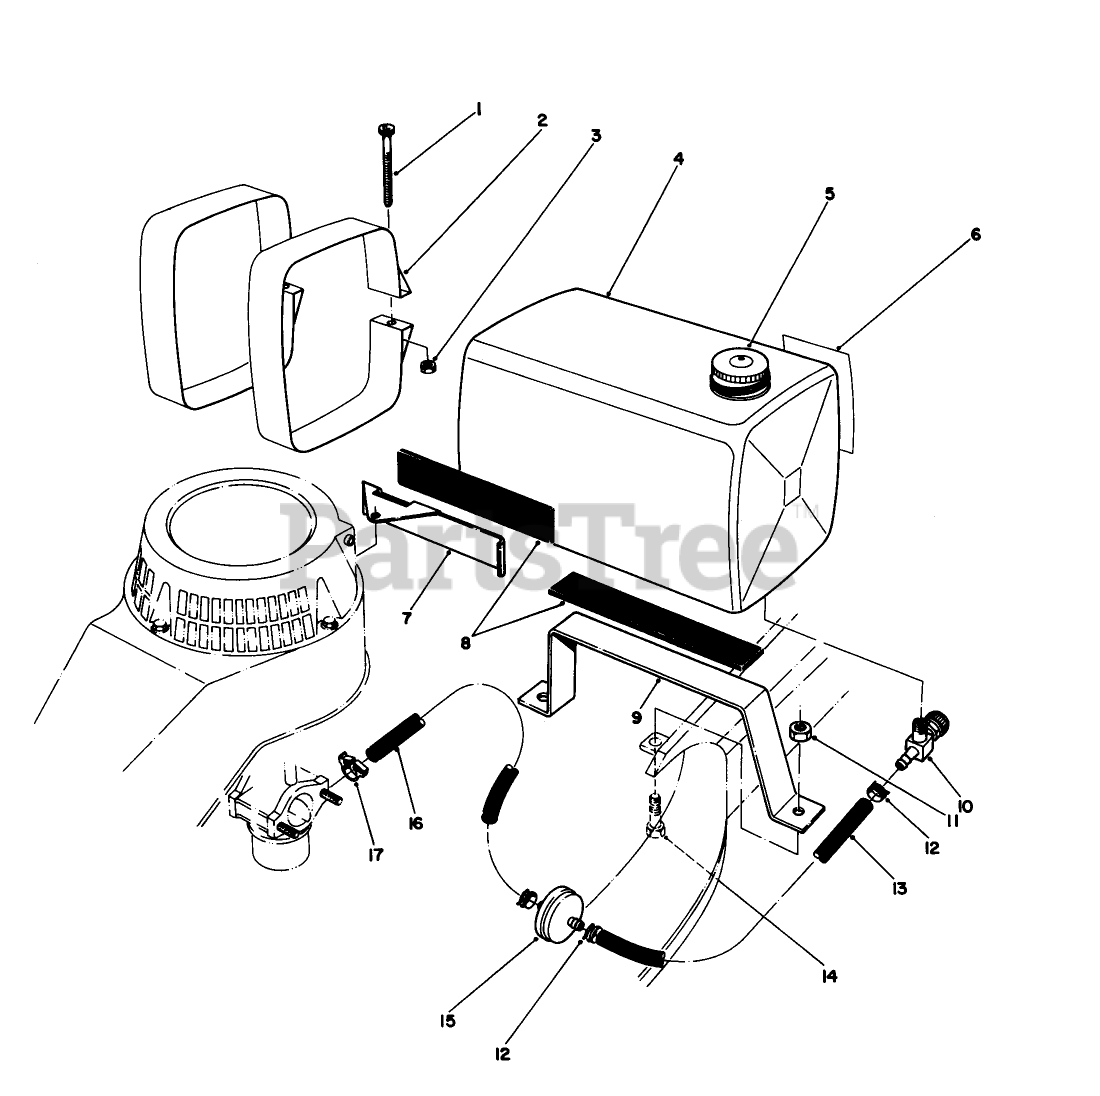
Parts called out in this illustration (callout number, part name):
1	SCREW-HSH
2	TANK MTG STRAP WA
3	NUT-HEX
7	FRT TANK MOUNT *
8	ISOLATOR PAD
11	NUT-LOCK, NI
13	HOSE-FUEL
14	SCREW-HH
16	HOSE-FUEL
